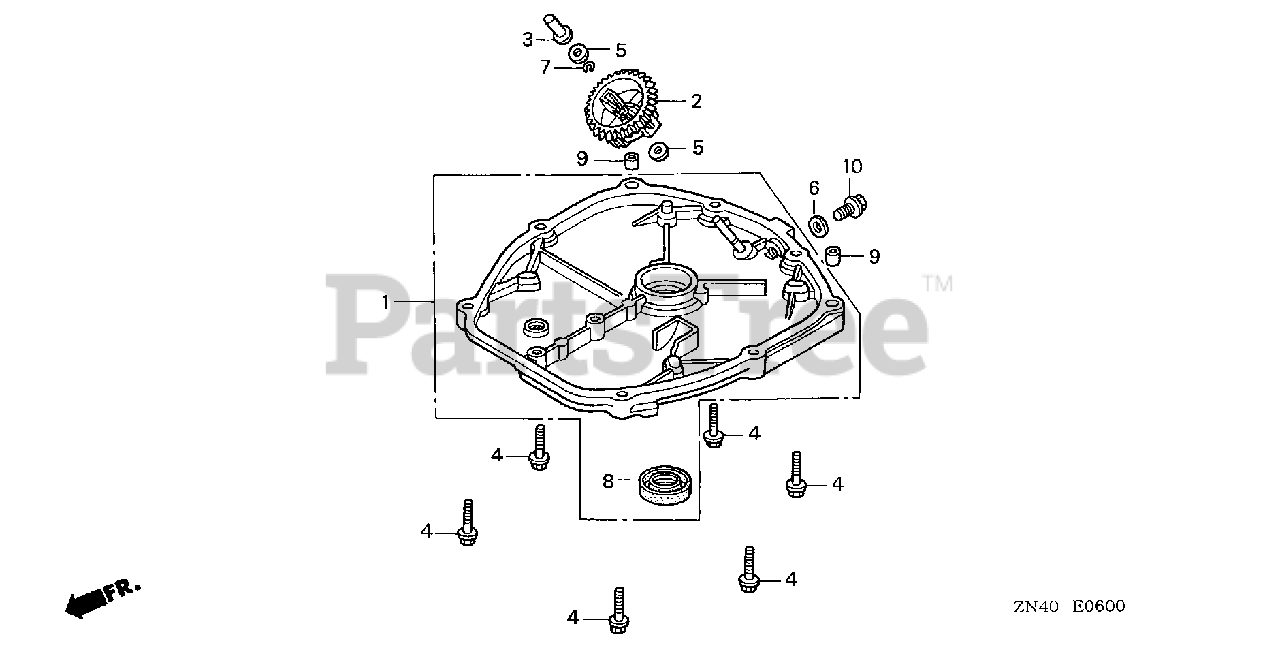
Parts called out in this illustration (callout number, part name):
1	COVER, CRANKCASE SIDE
2	GOVERNOR ASSY.
3	SLIDER, GOVERNOR
4	BOLT, FLANGE (5X23)
5	WASHER (4.2X13)
6	GASKET (8MM)
7	CLIP, GOVERNOR HOLDER
8	OIL SEAL (17X27X5) (KOYO)
9	PIN, DOWEL (6X10)
10	BOLT, FLANGE (8X12)
